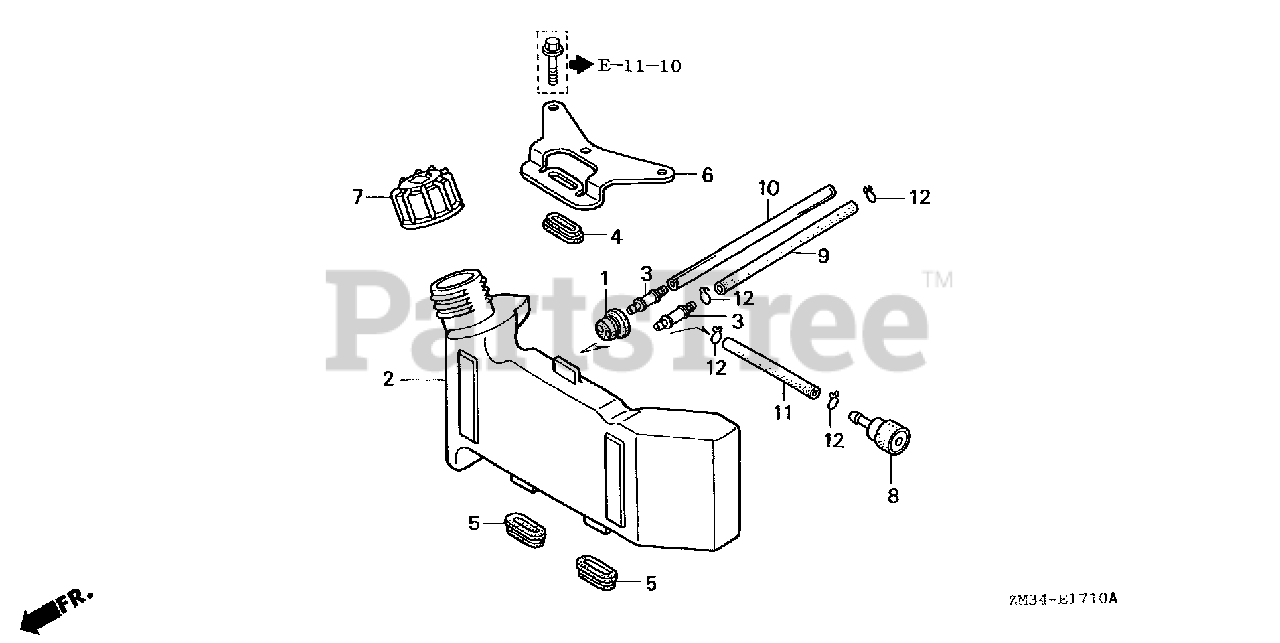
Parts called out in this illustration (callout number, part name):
1	GROMMET, FUEL TUBE
2	TANK, FUEL
3	FITTING
4	RUBBER A, TANK MOUNTING
5	RUBBER B, TANK MOUNTING
6	STAY, FUEL TANK
7	CAP ASSY., FUEL TANK
8	FILTER, FUEL
9	TUBE, FUEL
10	TUBE, FUEL RETURN
11	TUBE, FUEL
12	CLIP, TUBE
